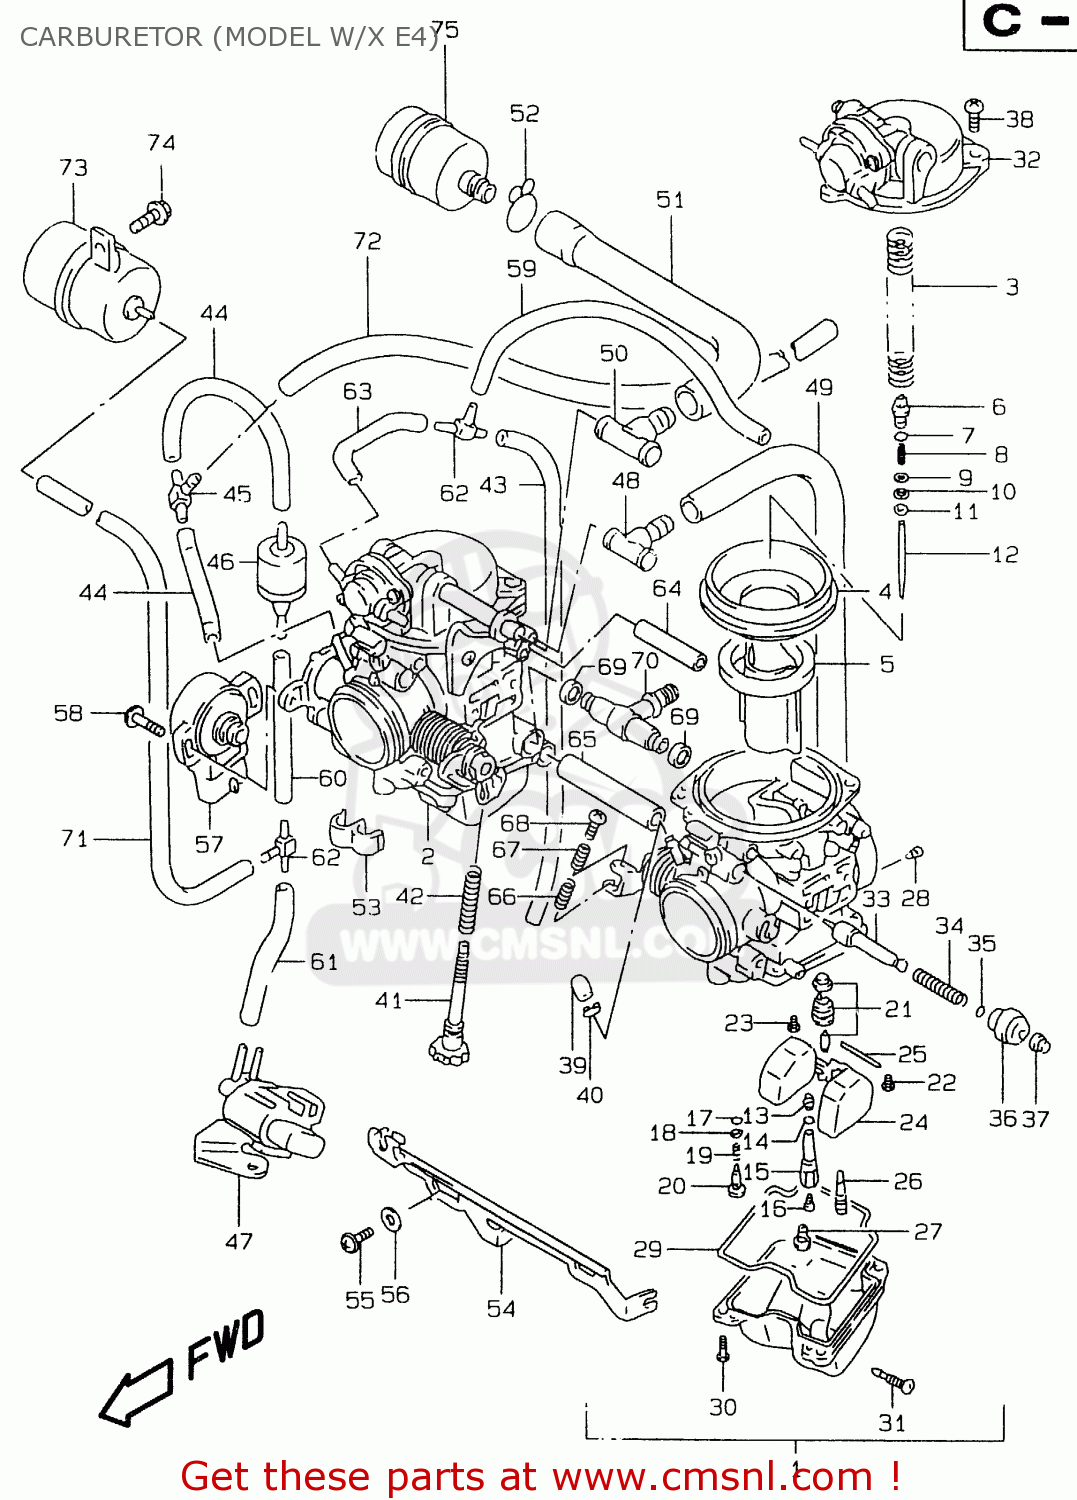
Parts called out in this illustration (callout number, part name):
1	CARBURETOR ASSY, LH
2	CARBURETOR ASSY, RH
3	SPRING
4	DIAPHRAGM
5	VALVE,PISTON
6	HOLDER
7	O RING(D:1.9,ID:4.8)
8	SPRING
9	WASHER
10	E RING,MULTIPLE JET NOZZLE
11	RING
12	NEEDLE,JET
13	JET,NEEDLE(P-5)
14	O RING
15	HOLDER,JET
16	JET,MAIN(130)
17	O RING,PILOT AIR SCREW
18	WASHER
19	SPRING,THROTTLE SCREW
20	ADJUSTER
21	VALVE ASSY,NEEDLE(NI)
22	SCREW
23	SCREW
24	FLOAT ASSY
25	PIN,FLOAT
26	JET,PILOT(17.5)
27	JET,MAIN(60)
28	JET,PILOT AIR(170)
29	GASKET (NAS)
30	SCREW
31	PLUG, DRAIN
32	COVER ASSY,DIAPHRAGM,L
33	PLUNGER
34	SPRING
35	O RING
36	GUIDE SCREW,PLUNGER
37	CAP,STARTER VALVE
38	SCREW
39	CAP
40	CLIP
41	ADJUSTER
42	SPRING
43	HOSE(3.5X7.5X600)
44	HOSE
45	NIPPLE
46	VALVE,CHECK
47	VALVE ASSY,3WAY SOLENOID
48	HOSE
49	HOSE
50	3 WAY
51	HOSE
52	CLIP
53	CLAMP
54	LEVER
55	SCREW
56	PACKING
57	SENSOR ASSY,THROTTLE
58	SCREW, SENSOR
59	HOSE(3.5X7.5X600)
60	HOSE(3.5X7.5X600)
61	HOSE(3.5X7.5X600)
62	3 WAY
63	HOSE(3.5X7.5X600)
64	ROD
65	PIPE
66	SPRING,THROTTLE SCREW
67	SPRING
68	SCREW
69	SEAL
70	NIPPLE
71	HOSE(3.5X7.5X600)
72	HOSE(5X10X600)
73	CHAMBER,VACUUM
74	BOLT
75	FILTER,2ND AIR CLEANER
